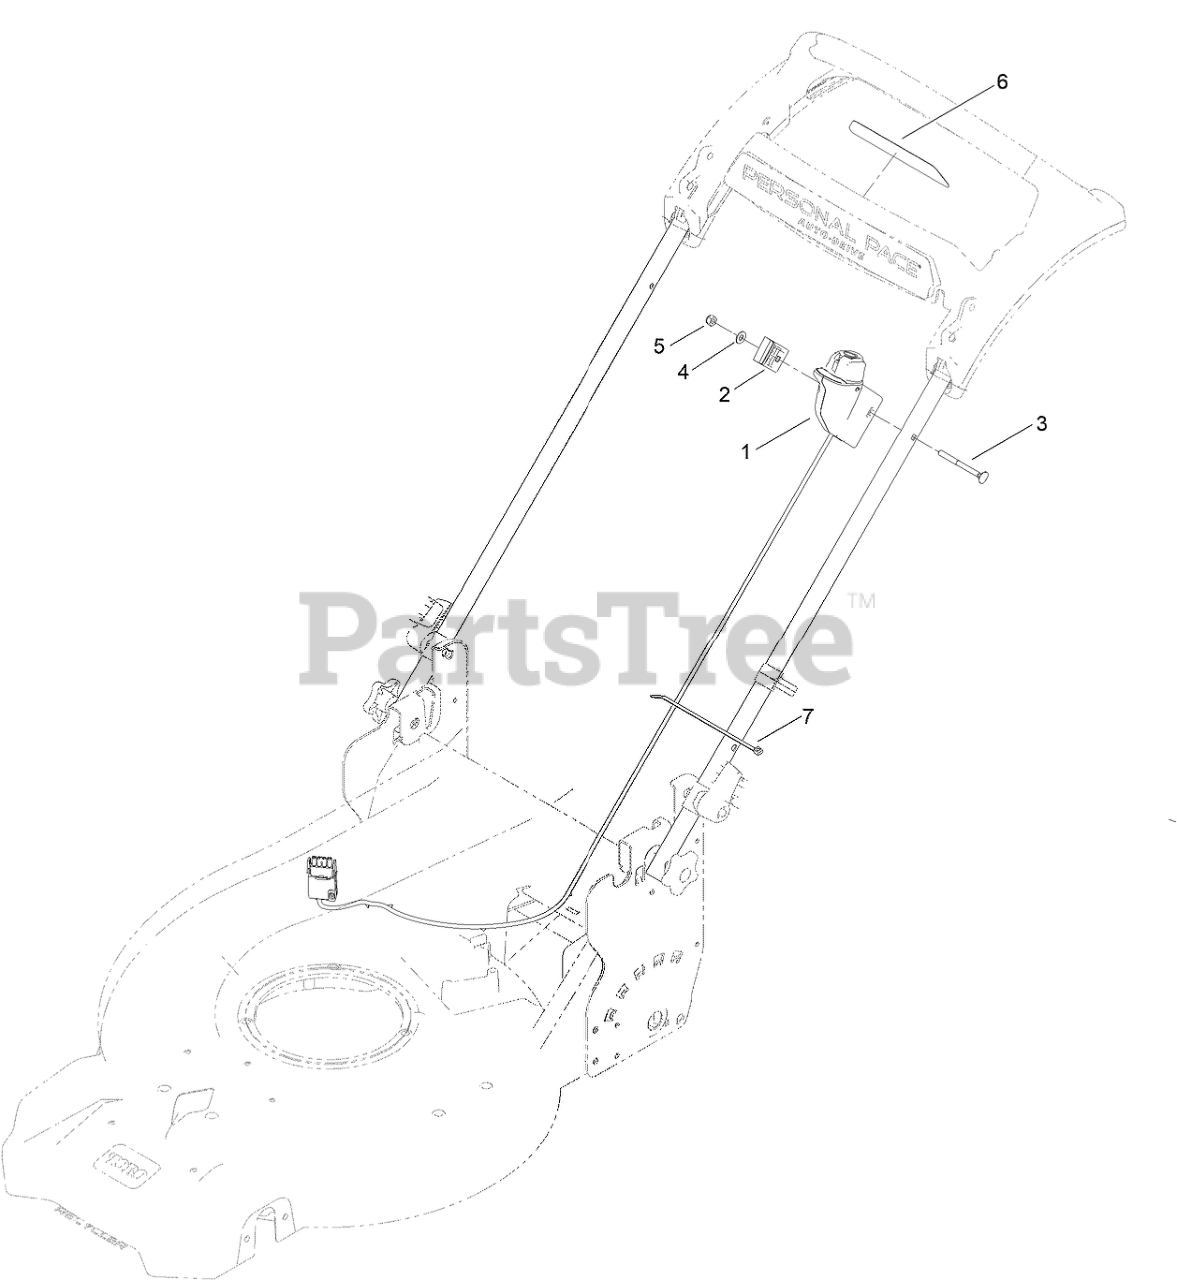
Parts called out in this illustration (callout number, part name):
1	STARTER SWITCH ASM
2	CLAMP-CABLE
3	SCREW-HANDLE
4	WASHER-FLAT
5	NUT-LOCK, NI
6	DECAL-CONTROLS (60V, START)
7	TIE-CABLE
